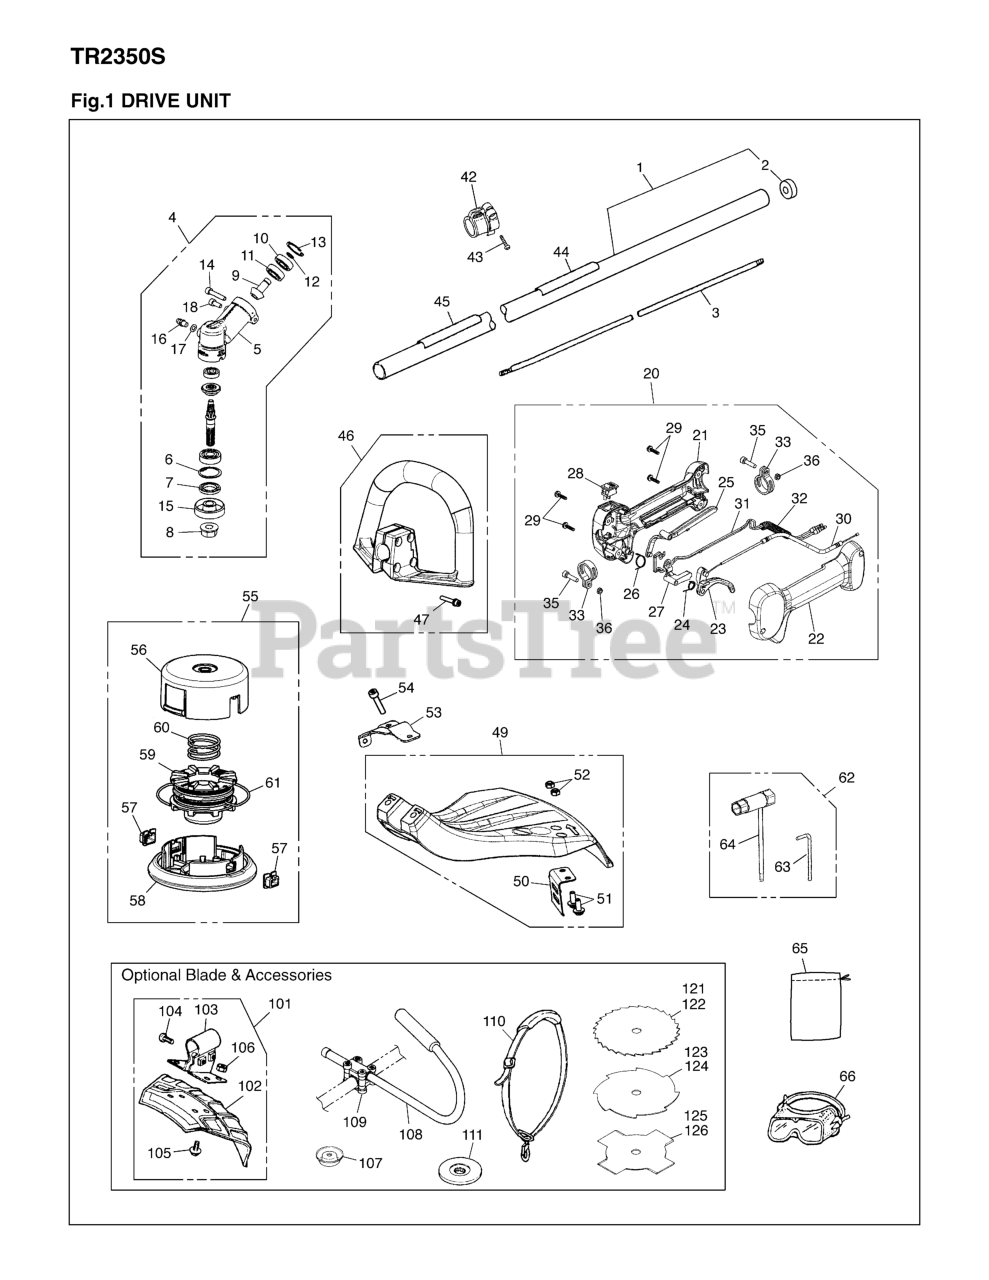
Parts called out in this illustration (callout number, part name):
1	PIPE COMP.
2	SEAL
3	SHAFT
4	GEARCASE ASSY.
5	GEARCASE
6	SNAP RING
7	SEAL
8	NUT
9	PINION
10	BEARING
11	BEARING
12	SNAP RING
13	RING, SNAP, M24 x 1.2
14	BOLT
15	HOLDER (A)
16	FITTING, GREASE
17	WASHER, FITTING
18	BOLT
20	GRIP ASSY
23	LEVER, THROTTLE
24	SPRING, THROTTLE
25	LEVER, SAFETY
27	LEVER, JOINT
28	SWITCH
29	SCREW
30	CABLE COMP
31	CORD COMP
32	TUBE
35	BOLT TORX
42	HANGER COMP.
43	SCREW
44	LABEL, NAME
45	LABEL, CAUTION
46	HANDLE ASSY
47	SCREW
49	GUARD ASSY FOR T
51	SCREW
54	BOLT, TORX
55	TAP HEAD COMP.
56	CASE
57	EYELET
58	COVER
59	CORD HOLDER
60	SPRING
62	TOOL SET
63	BAR
66	GOGGLE
101	GUARD ASSY.
102	GUARD
104	BOLT
105	SCREW
106	NUT M6
107	COVER
108	HANDLE, J
109	BRACKET
110	STRAP ASSY
111	HOLDER (B)
121	BLADE, 9
122	BLADE, 9
123	BLADE, 8
124	BLADE, 9
125	BLADE, 8
126	BLADE, 9
